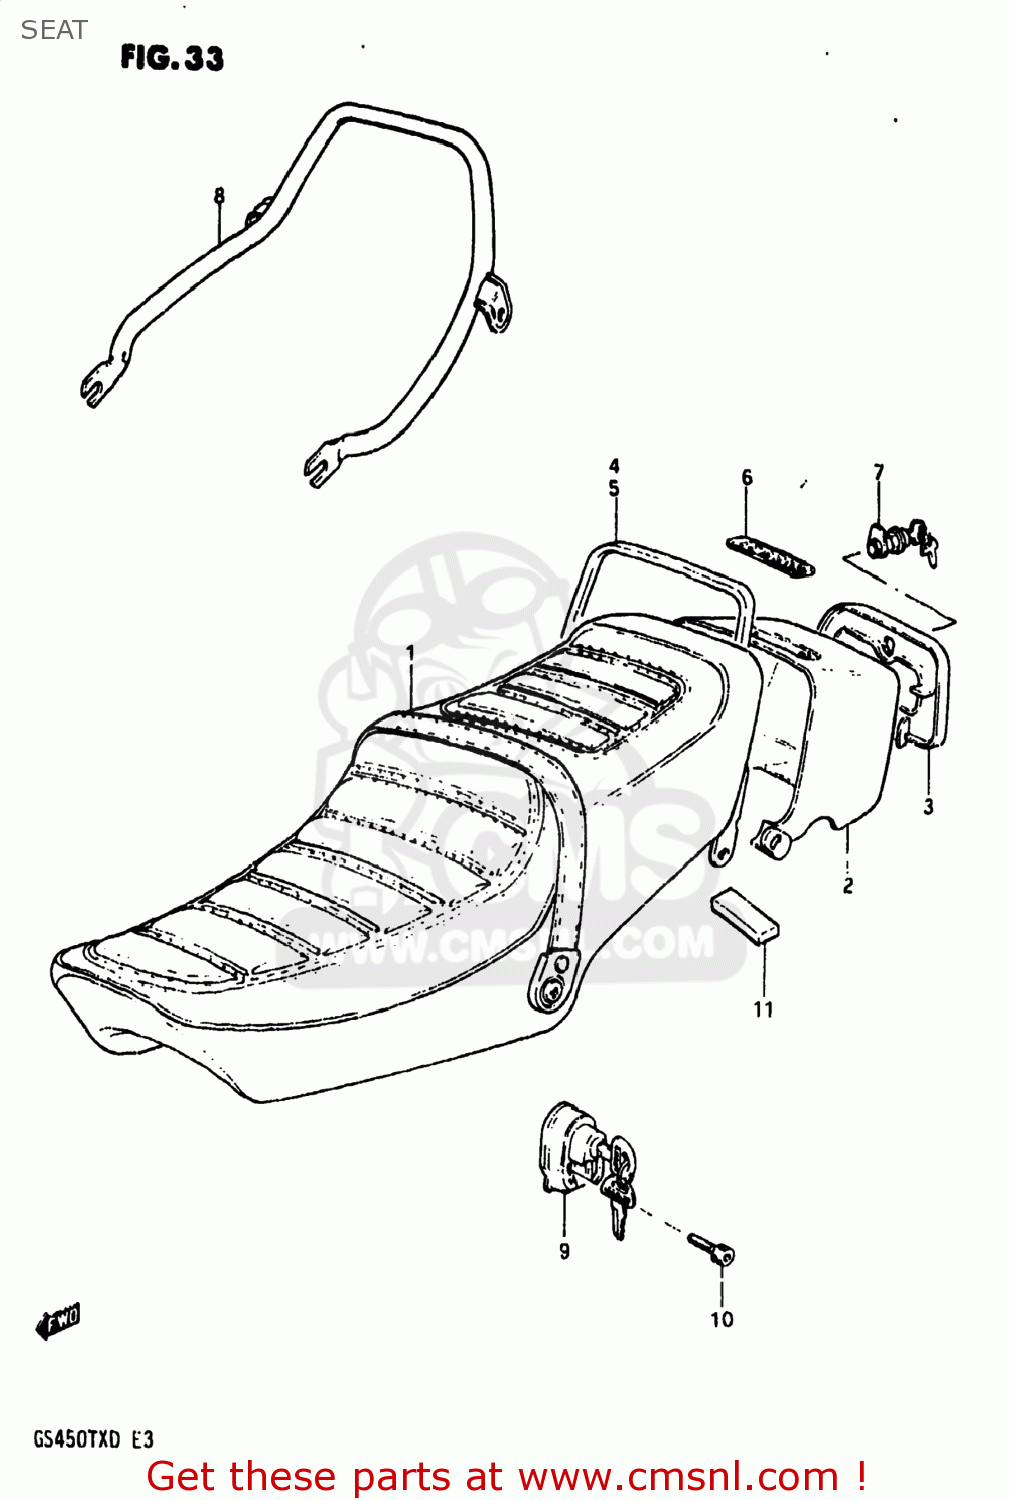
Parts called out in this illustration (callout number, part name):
1	SEAT ASSEMBLY
2	COVER,SEAT TAIL
3	LID,TAIL COVER
4	WEATHERSTRIP,TAIL COVER
5	WEATHER STRIP, TAIL COVER NO.2
6	EMBLEM
7	LOCK SET,TAIL COVER
8	HANDLE,PILLION RIDER
9	LOCK ASSY,HELMET
10	BOLT 5X25
11	CUSHION
